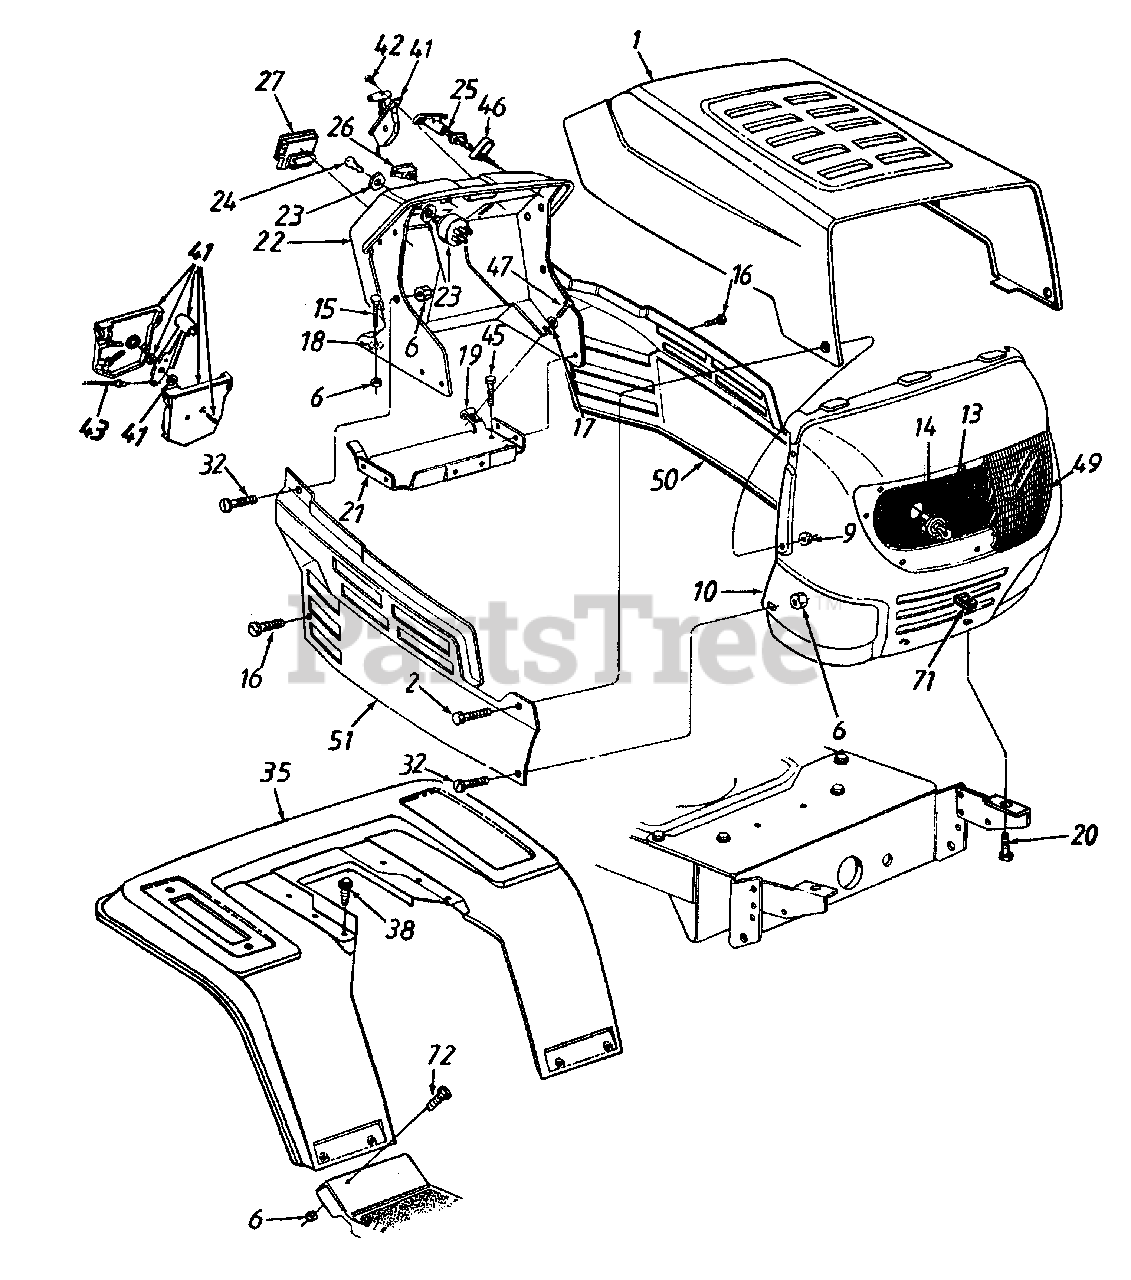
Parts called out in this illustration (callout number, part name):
6	Hex Sems Nut 1/4-20 Thd.
9	Flange L-Nut 1/4-20 Thd.
13	Lamp
14	Socket
15	Carriage Bolt 1/4-20 x .75" Lg.
16	Hex Wash. Hd. TT-Tap Scr. 1/4-20 x .5" Lg.
17	R-Wash..281" I.D. x .73" O.D.
18	Bolt Retainer 1/4" I.D.
19	Speed Nut 1/4-20 Thd.
20	Hex Bolt 5/16-18 x .75" Lg.
23	Ignition Switch
24	Ignition Key
25	Choke Control 23" Lg.
26	Light Switch
27	Ammeter
32	Truss Mach. Scr. 1/4-20 x .5" Lg.
41	Throttle Box Ass'y.
42	Truss Mach. AB-Tap Scr. #10 x .5" Lg.
43	Throttle Control Wire 18.5" Lg.
45	Hex Wash. Hd. B-Tap Scr. 5/16-18 x .5" Lg.
46	Choke Retainer
47	Hex TT-Tap Scr. 1/4-20 x .75" Lg.
49	Lens
